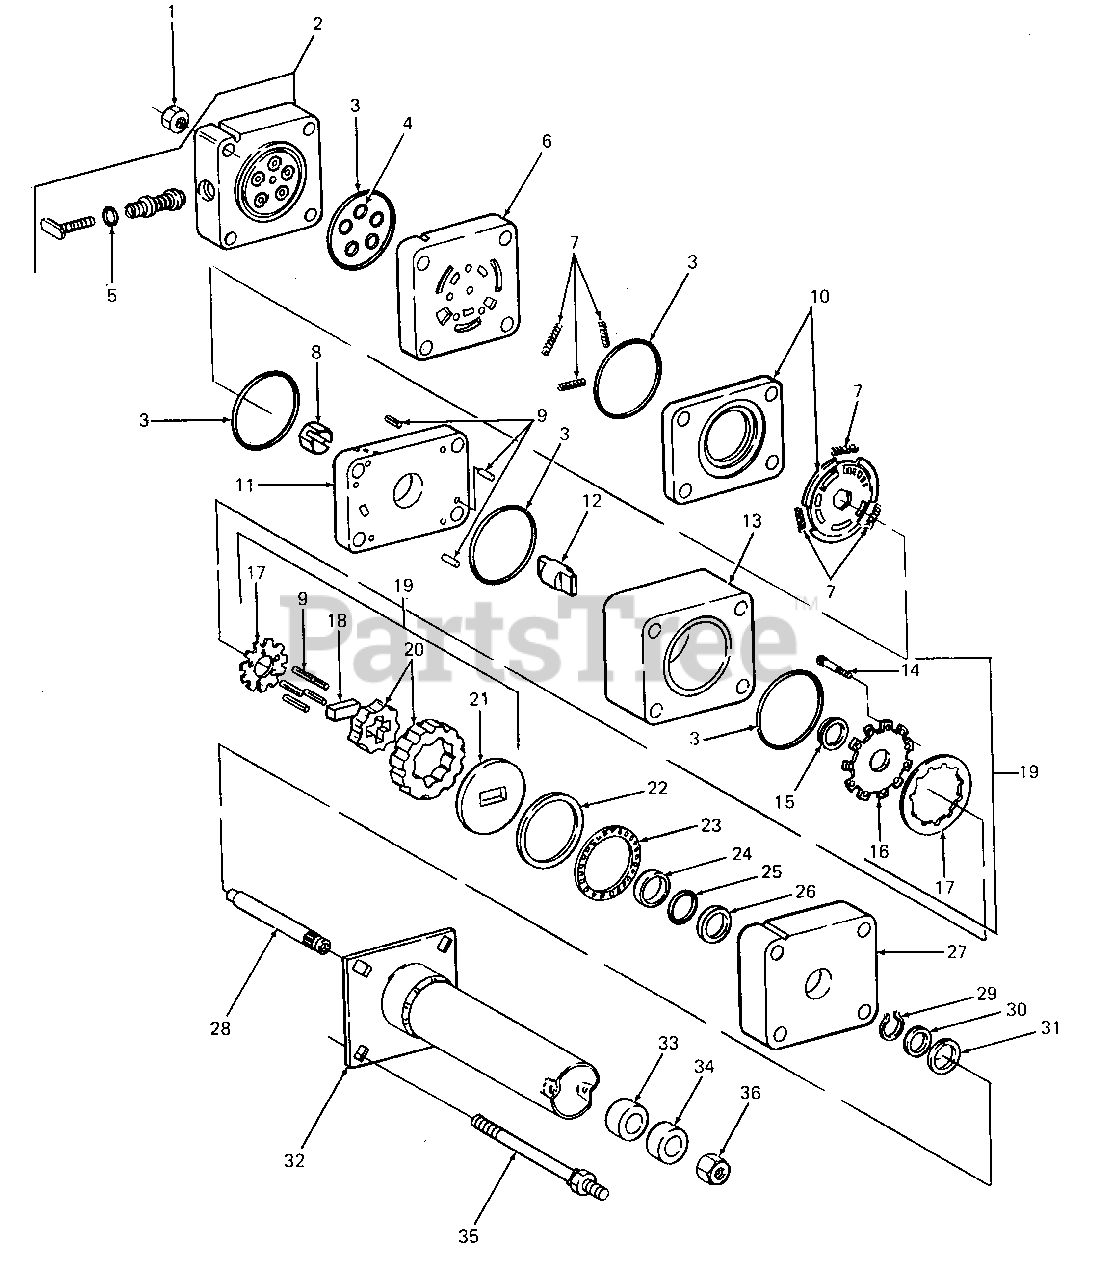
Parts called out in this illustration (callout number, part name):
1	Nut, Hex, 5/16-24
2	Power Cover & Check Valve Assy
3	Ring, Seal
6	Manifold, Port
8	Drive Assy, Hex
9	Roller Kit, Needle
10	Valve & Ring Assy
11	Manifold, Isolation
13	Ring, Metering
16	Cover, Commutator
17	Commutator & Ring Assy
18	Spacer, Drive Link
19	Metering Assy
23	Bearing, Thrust
24	Seal, Face
25	Ring, Back-up
26	Seal, Spacer
27	Plate, Upper Cover
28	Input Shaft Assy
29	Ring, Retaining
31	Plate, Retaining
32	Upper Cover & Tube Assy
33	Bearing, Column
34	Dust Seal, Column
35	Bolt, Special
36	Hex Jam Nut, 5/8-18
